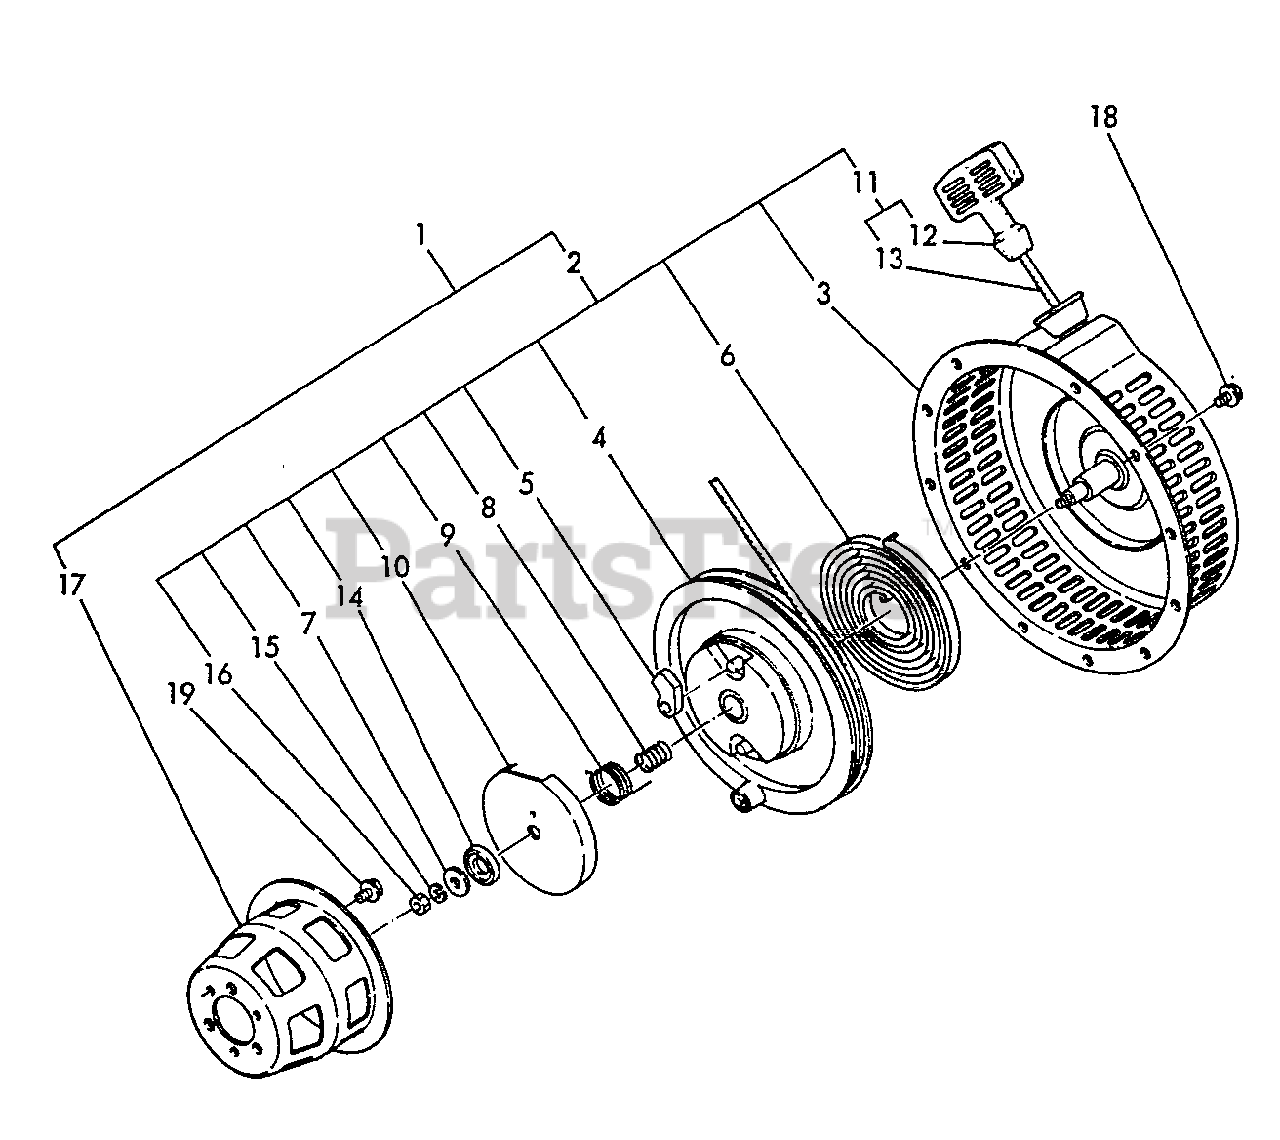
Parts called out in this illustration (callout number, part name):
1	STARTER ASSY, RECOIL
2	STARTER ASSY, RECOIL
3	CASE, STARTER
5	RATCHET
6	SPRING
7	WASHER, THRUST
8	SPRING, FRICTION
9	SPRING, RETURN
10	PLATE, FRICTION
11	STARTER ROPE ASSY
12	GRIP, STARTER
13	ROPE, STARTER
14	WASHER, THRUST
15	LOCKWASHER - 6
17	REEL, ROPE
18	BOLT - 6×8 -- PLATED
19	BOLT - 6×12 -- PLATED
